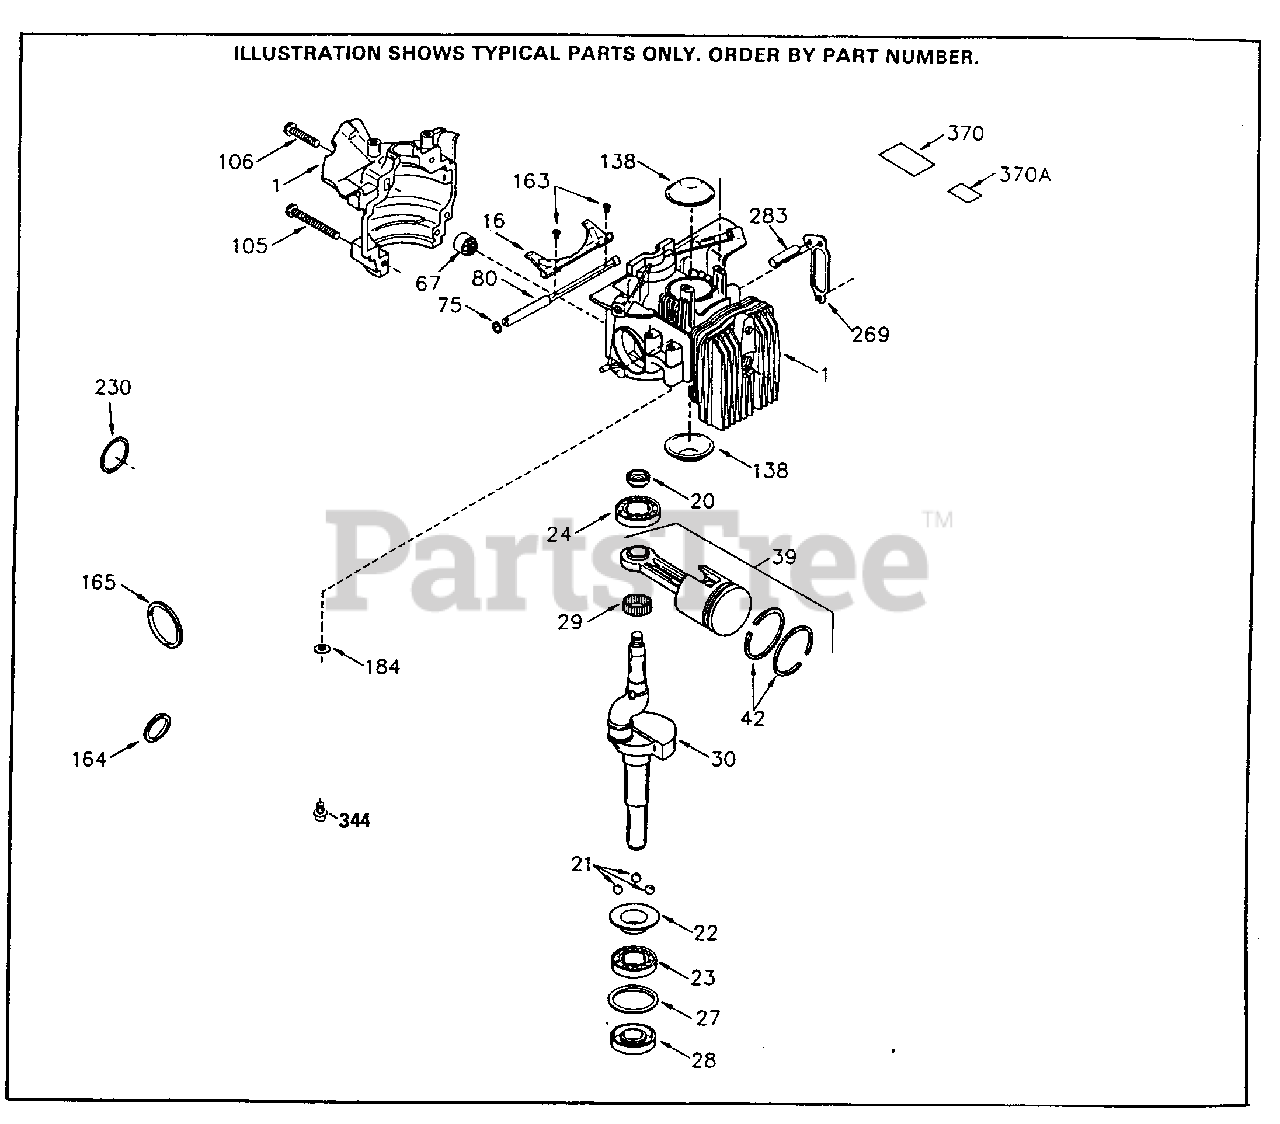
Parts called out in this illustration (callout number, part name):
1	"Cylinder (Incl. 67, 105, 106 & 138)
16	Lever, Governor
20	Seal, Oil (flywheel end)
22	Ring, Slide
23	Bearing, Ball
24	Bearing, Ball
27	Retainer, Bearing
28	Seal, Oil (PTO end)
29	Bearing Strip (31 needles)
30	Crankshaft
39	Piston & Rod Assy. (Incl. 29 & 42)
42	Ring Set, Piston
67	Filter, Fuel (w/brass collar)
75	Seal, Oil
80	Shaft, Governor
105	Screw, 5/16-18 x 1-5/8"
106	Screw, 5/16-18 x 2-3/16"
138	Cover, Port
163	Screw, 4-40 x 3/16"
164	"O" Ring
165	"O" Ring
184	Gasket
230	"O" Ring
269	Gasket, Muffler
283	Pin, Spirol
344	Screw, 5/16-18 x 5/8"
370	Decal, Fuel mix
370A	Decal, Model & Serial No.
